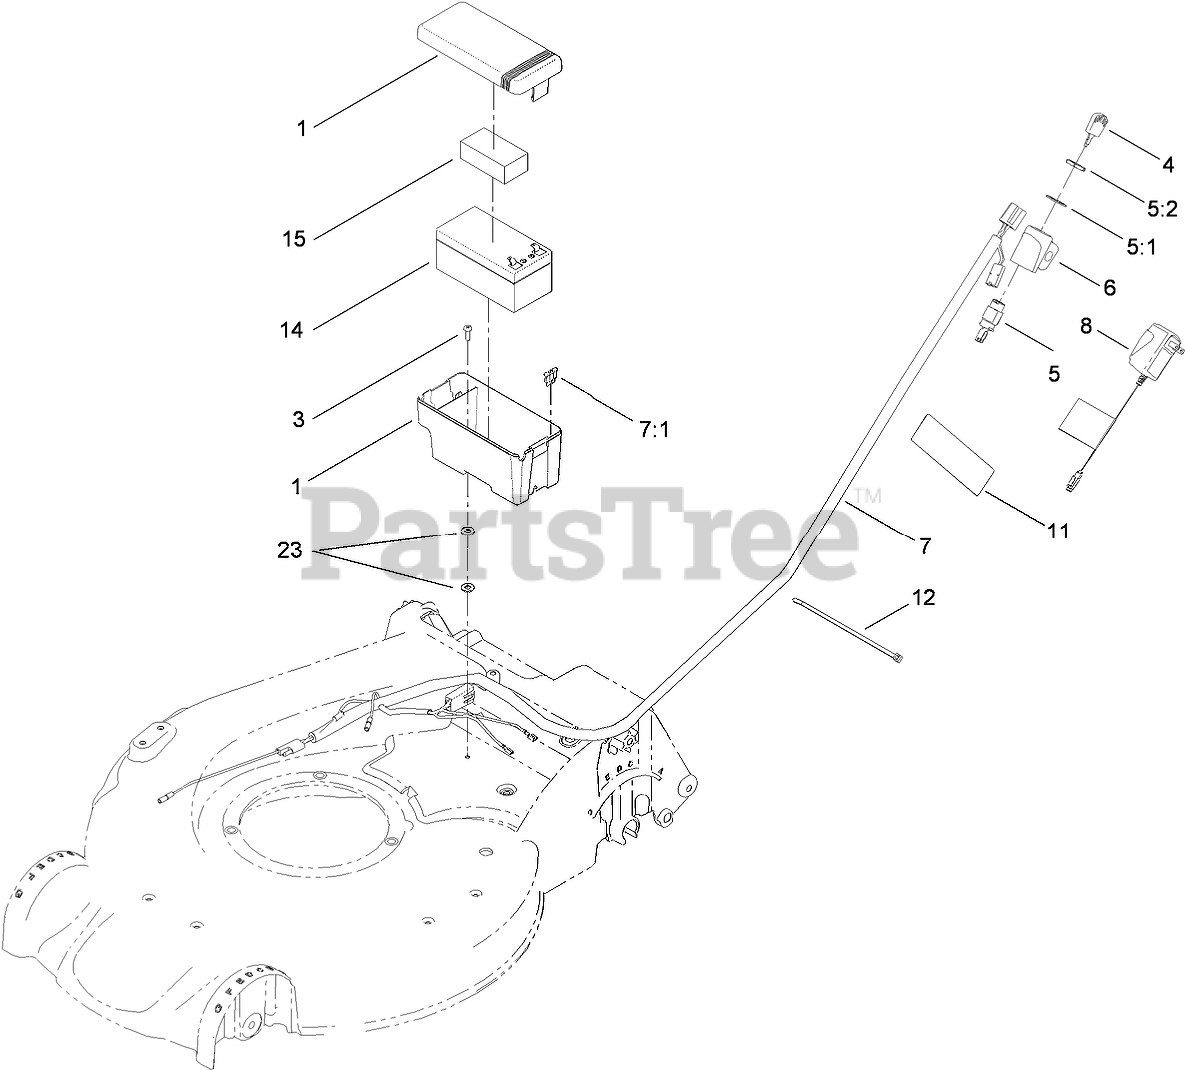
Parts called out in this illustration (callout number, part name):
1	BATTERY BOX ASM
5	STARTER SWITCH ASM
5:1	WASHER-TOOTH, INTERNAL
5:2	NUT-HH
6	MOUNT-SWITCH
7	HARNESS-WIRE
7:1	FUSE-40 AMP
8	CHARGER-BATTERY
11	DECAL-WARNING
12	TIE-CABLE
14	BATTERY-WET
15	FOAM-BATTERY, TOP
23	WASHER-FLAT
